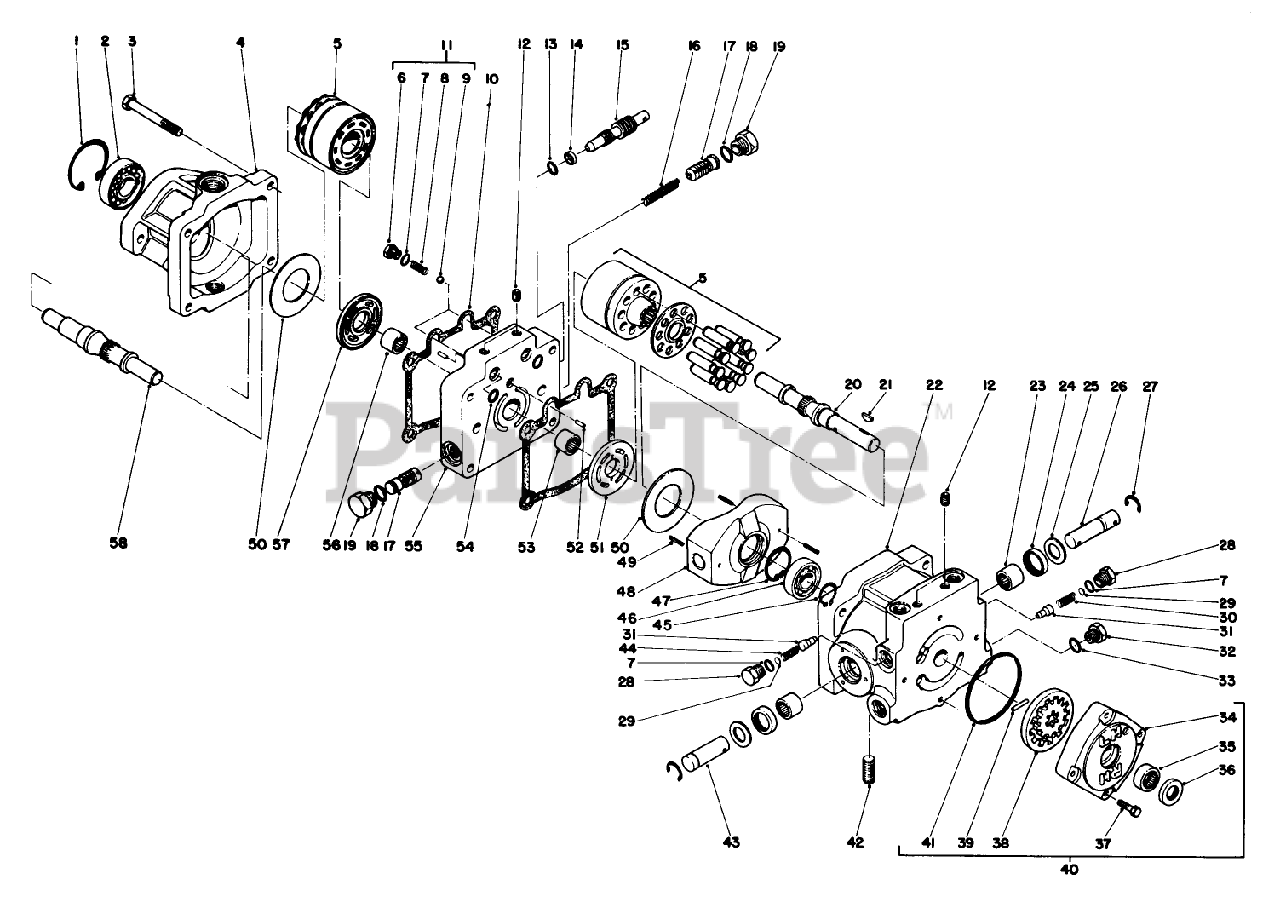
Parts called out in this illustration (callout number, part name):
1	RING-SNAP
2	BEARING
3	SCREW-HH
4	Motor Housing
5	Cylinder Block Kit
6	PLUG-VALVE, CHECK
7	O-RING
8	SPRING-VALVE
10	GASKET
11	Check Valve Kit (Incl. Ref. #6-9)
12	PLUG-PIPE
13	O-RING
14	RING-BACK UP
15	By Pass Valve
16	SPRING-VALVE
17	VALVE ASM
18	O-RING
19	PLUG-HYD, HH
20	Pump Shaft
21	KEY-WOODRUFF
22	PUMP HSG
23	BEARING-NEEDLE
24	SEAL-LIP
25	WASHER-FLAT
26	SHAFT-TRUNNION
27	RING-RETAINING
28	PLUG-HH
29	PACK-SHIM
30	SPRING-VALVE
31	Cone-Relief Valve
32	PLUG-HH
33	O-RING
34	HOUSING-PUMP, CHARGE
35	NEEDLE BRG
36	SEAL-OIL
37	SCREW-HH
38	Gerotor ASM
39	PIN-STRAIGHT, HEADLESS
40	Charge Pump (Incl. Ref. #34-39 & 41)
41	O-RING
42	UNION-FILTER
43	SHAFT-TRUNNION
44	SPRING-VALVE
45	RING-SNAP, EXT
46	BEARING-BALL
47	RING-RETAINING
48	PLATE-SWASH, VARIABLE
49	PIN-SPRING
50	PLATE-THRUST
51	PLATE-VALVE, PUMP
52	PIN-DOWEL
53	BEARING-NEEDLE
54	O-RING
55	Center Section
56	BEARING-SHAFT
57	PLATE-VALVE, MOTOR
58	SHAFT-MOTOR
